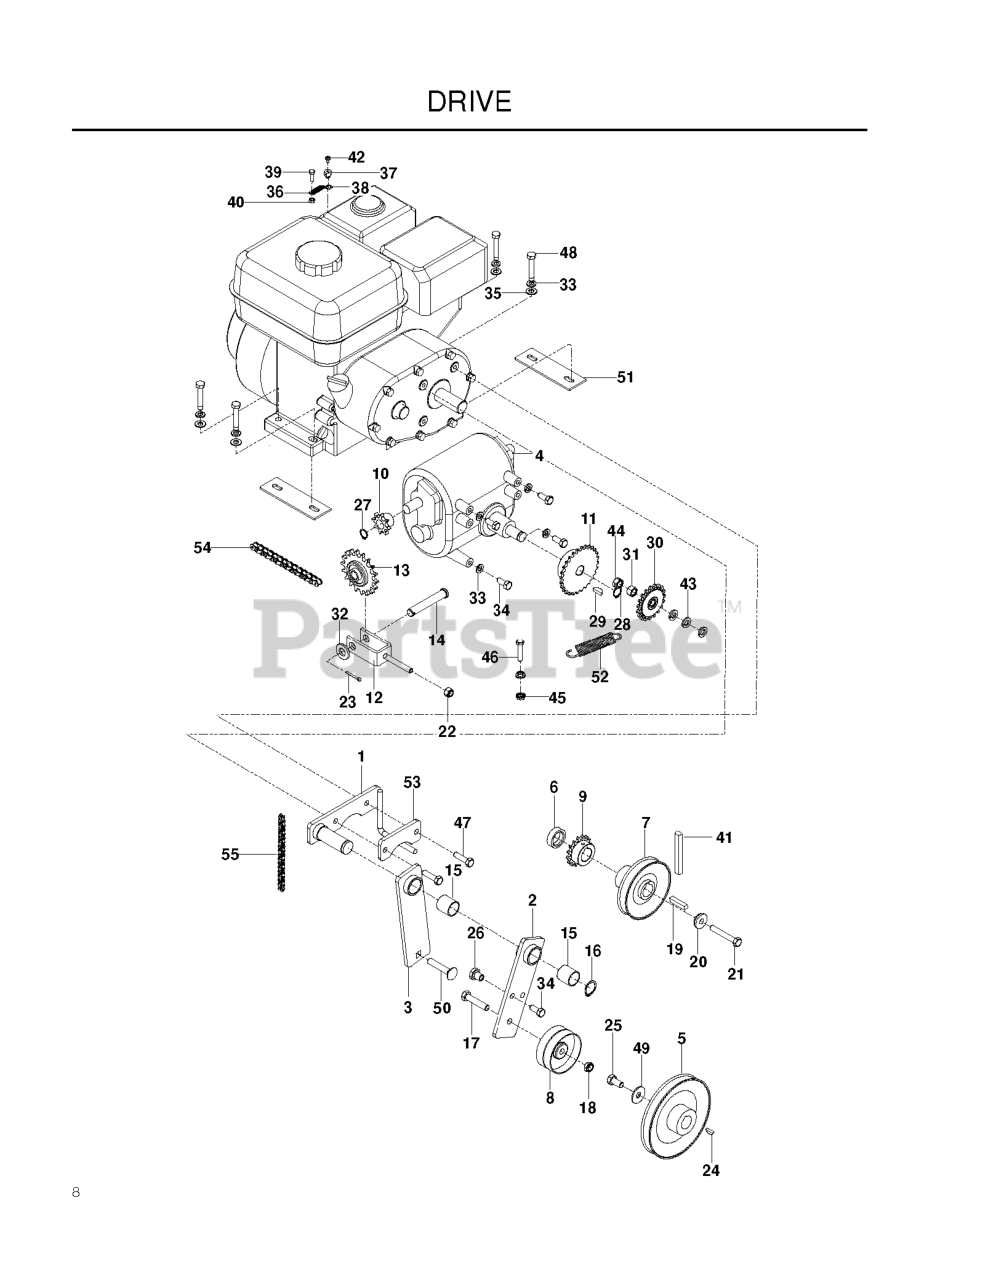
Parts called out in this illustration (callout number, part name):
1	IDLER PIVOT, BLACK
2	BELT IDLER W/BUSHING
3	CHAIN IDLER W/BUSHING
4	TRANSMISSION-4 SP SOD CUTTER
5	PULLEY - 5.25 A
6	SPACER - PTO SHAFT
7	PULLEY - 3.75 A
8	PULLEY, IDLER 2 3/4 OD PAINTED
9	SPROCKET, ENGINE
10	SPROCKET #40 CHAIN
11	SPROCKET, TRANSMISSION
12	KIT TENSIONER ASSY/DRIVE CHAIN
13	SPROCKET, CHAIN TENSIONER
14	PIN CLEVIS 1/2 X 3 ZD
16	RETAINING RING, 7/8"
17	HCS 3/8-16 X 1 3/4 GR5
18	NUT HEX 3/8-16 NYLON, THIN
19	KEY 7MM SQ X 33MM ENGINE
20	WASHER - STEPPED
21	HCS M8-1.25 X 55MM GR8.8 ZD
22	NUT 5/16 NYLOC
23	PIN COTTER 1/8 X 1 ZD
24	KEY-WOODRUFF, #6
25	HCS 3/8F X 3/4
26	SPRING ANCHOR
27	RING RETAINING 9/16 EXT PLAIN
28	RETAINER RING
29	KEY, #9 WOODRUFF
30	SPROCKET - IDLER 35 PITCH
31	NUT 3/8-16 NYLOC
32	WASHER 1/2" FLAT
33	WASHER.LOCK.HVY.HLCL.SPR.5/16
34	HCS 5/16C X 3/4
35	FLAT WASHER 5/16 SAE
36	SPRING, THROTTLE, HONDA ENGINE
37	CLAMP, THROTTLE CABLE
38	CLIP, THROTTLE HONDA
39	HCS M5-0.8 X 16MM GR 8.8 ZD
40	NUT 5MM-.8 HEX ZD
41	V-BELT, "A" 26" SPECIAL
42	SCREW METRIC SPECIAL X 1/4 ZN
43	SLW 3/8 STD
44	NUT 3/8C CENTERBLOCK
45	NUT 1/4-20 HEX FLG LK ZD
46	BOLT HEX 1/4 X 1-1/4
47	HCS M8-1.25 X 30MM
48	HCS 5/16C X 1 3/4
49	SPRING WASHER - .38
50	RHSNB 3/8C X 2
51	PLATE KIT, ENG, HONDA &5.5 B&S
52	SPRING AXLE AERATOR
53	KEEPER - CHAIN, BLACK
54	CHAIN,TRANSMISSION #35
55	CHAIN, 57.5 TRANS #40
